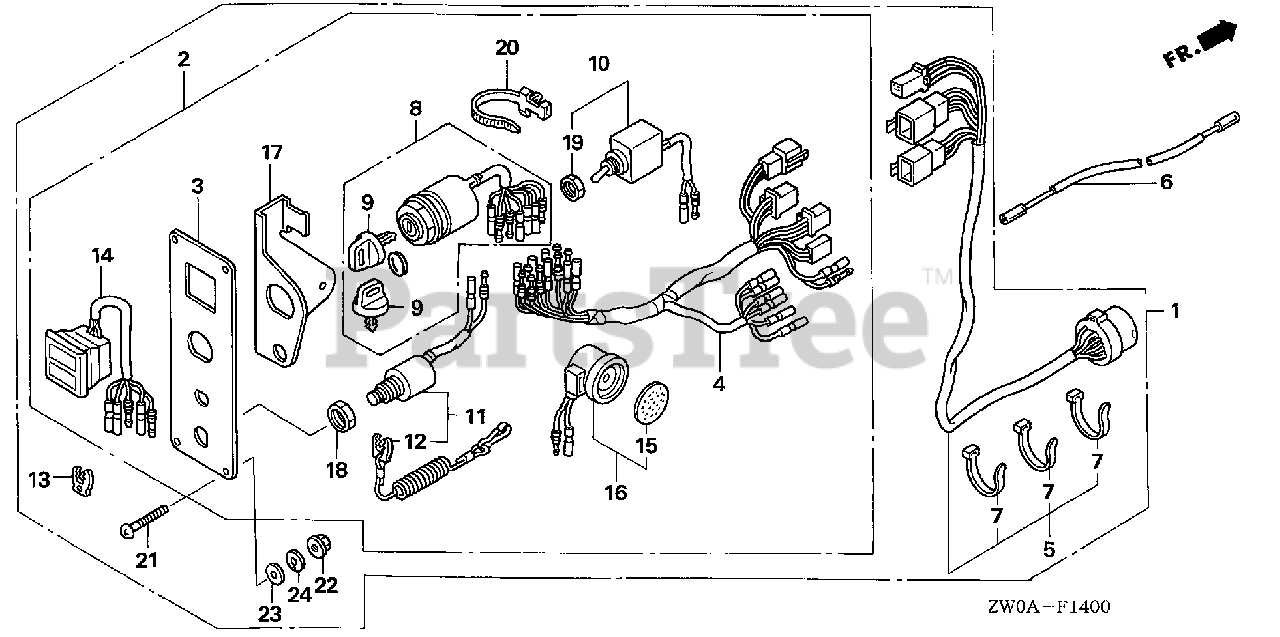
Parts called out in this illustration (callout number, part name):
1	PANEL KIT, SWITCH (SINGLE)
2	PANEL ASSY., CONTROL
3	PANEL, CONTROL
4	HARNESS ASSY., SWITCH PANEL
5	CABLE ASSY., SWITCH PANEL
6	WIRE ASSY., GROUND (BONDING)
7	TIE, CABLE (NATURAL 2.4X92)
8	SWITCH ASSY., COMBINATION
9	KEY ASSY., COMBINATION SWITCH
10	SWITCH ASSY., SOLENOID
11	SWITCH ASSY., EMERGENCY STOP
12	WIRE, EMERGENCY
13	CLIP, EMERGENCY LOCK
14	LAMP ASSY., INDICATION (2-LED)
15	PLATE, TURN SIGNAL BUZZER
16	BUZZER, WARNING
17	BRACKET, BUZZER
18	NUT, HEX. (16MM)
19	NUT, HEX. (12MM)
20	BAND, WIRE HARNESS (150MM)
21	SCREW, PAN (5X40)
22	NUT, FLANGE (5MM)
23	WASHER, PLAIN (5MM)
24	WASHER, SPRING (5MM)
